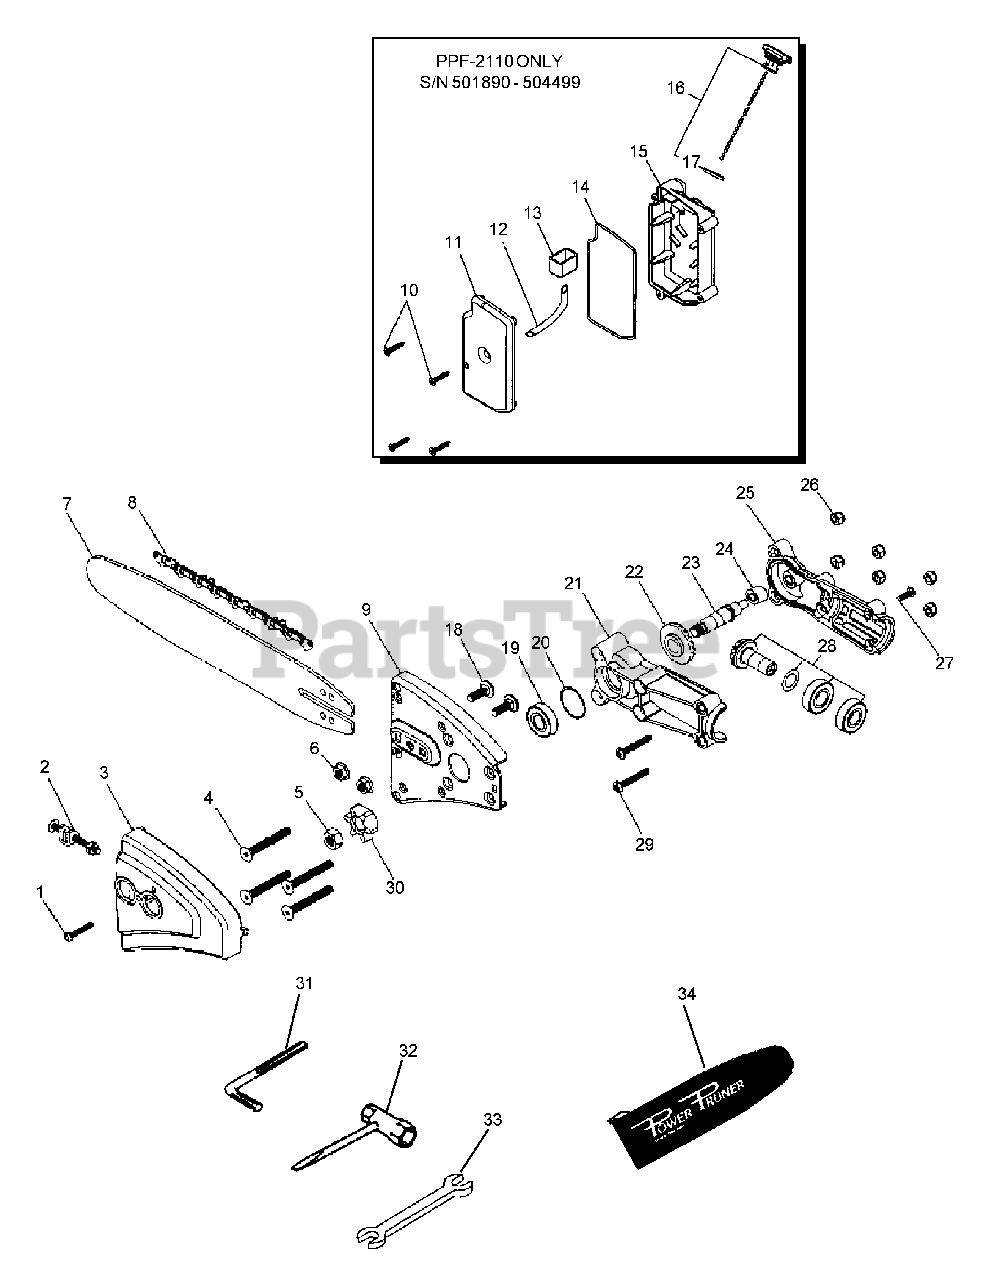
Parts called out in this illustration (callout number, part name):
1	SCREW - 8-32×1" - TORX PAN HEAD
2	TENSIONER KIT
3	GUARD, SPROCKET
4	SCREW - TORX FLAT HEAD
5	NUT, HEX
6	NUT - FLANGE
7	GUIDE BAR - 10"
8	SAWING CHAIN - 91VS - 10" -- LOW PROFILE
9	SAW BAR CARRIER
10	SCREW, PH. F.H. M.S.
11	TANK, OIL
12	PIPE, FUEL 3x-5x-70 BLACK
13	CUP, OIL
14	O-RING
15	TANK, OIL
16	CAP, OIL
17	O-RING
18	BOLT, CARRIAGE
19	BEARING, BALL 6001 DDU
20	SHIM 0.004"
21	CASE, GEAR - RIGHT
22	GEAR, BEVEL
23	SHAFT, GEAR
24	GUIDE, DRIVESHAFT
25	CASE, GEAR - RIGHT
26	NUT, LOCK 10-24 UNC
27	SCREW - TORX PAN HEAD
28	SHAFT, GEAR
29	SCREW, TORX 10-24 UNC 1-1/4
30	SPROCKET
31	TOOL, DRIVER
32	TOOL, BOX SPANNER
33	SPANNER 8×10
34	COVER, GUIDE BAR
